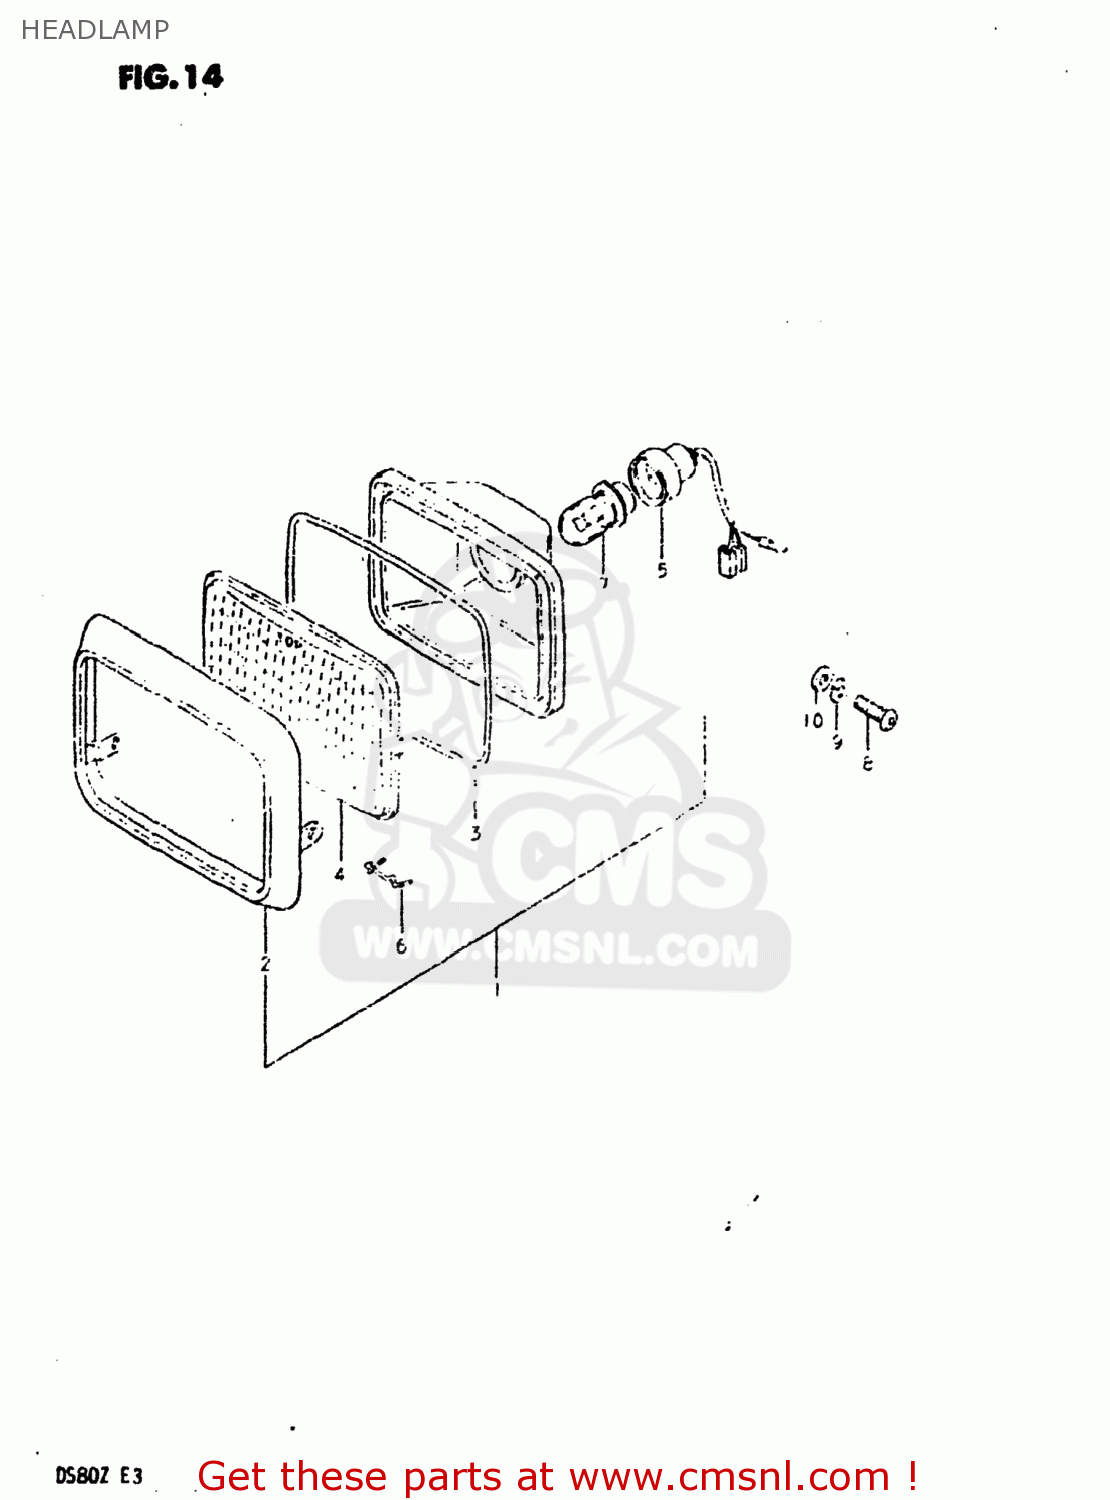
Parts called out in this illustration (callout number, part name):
1	LAMP ASSEMBLY,HEAD
2	RIM,HEADLAMP
3	GASKET,HEADLAMP LENS (NAS)
4	LENS,HEADLAMP (PLASTIC)
5	SOCKET,BULB
6	SPRING,HEADLAMP UNIT
7	BULB(6V15/15W/STANLEY,A3598HA)
8	SCREW
9	LOCK WASHER
10	WASHER
